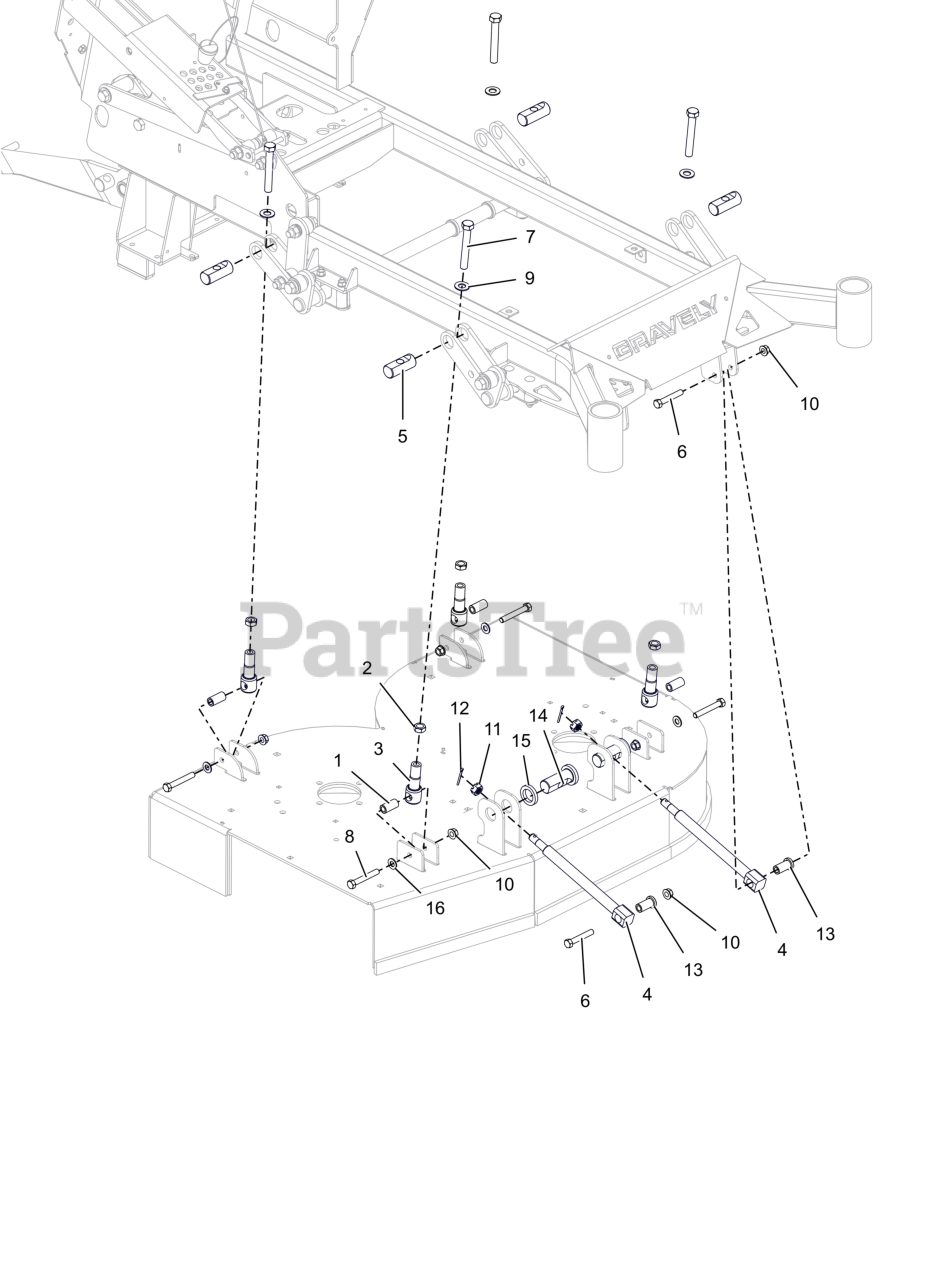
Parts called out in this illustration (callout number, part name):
1	SPACER, DECK LEVELING
2	NUT-JAM .500-13 G2 ZCC
3	LINK, DECK LIFT FORMED
4	DRAG,LINK-HD
5	PIN, DECK LIFT
6	BLT,HEX .38-16X2.25 G5 ZCC
7	BLT, HEX 0.5-13X3.5F GR5 ZCC
8	BLT, HEX .38-16X2.50 G8 ZCC
9	WSHR, FLT .557X1.040X.102 ZCC
10	NUT-LK-CTR-FLG .375-16 GF ZCC
11	NUT-SL .50-13
12	PIN,CTR.12X1.25EXTPRSQCT ZC120
13	SPCR, DRAG LINK
14	PIN, DECK LIFT
15	WSHR-FL-STL 1.0X1.50X.25
16	WSHR,FLT .406X.812X.065 ZCC
